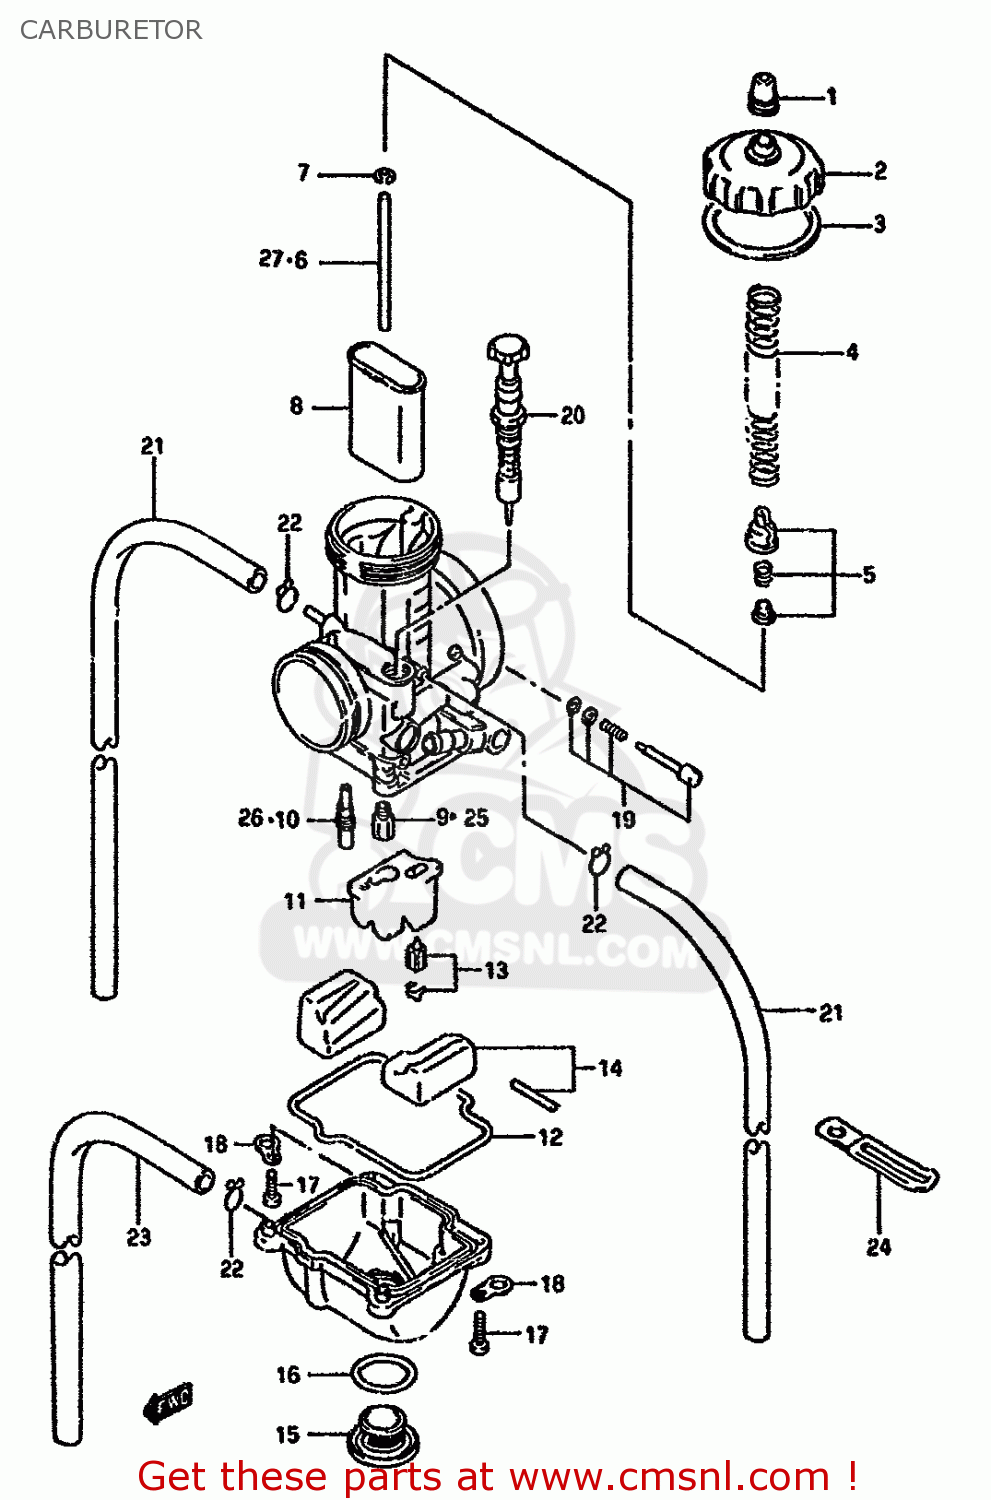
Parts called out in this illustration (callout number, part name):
1	CAP,CARBURETOR
2	CAP,TOP
3	GASKET,TOP CAP
4	SPRING
5	HOLDER SET,CABLE
6	NEEDLE(R1471MS)
7	CLIP,NEEDLE
8	VALVE,PISTON(CA:5.0)
9	JET,MAIN(155)
10	JET,SLOW(55)
11	HOLDER
12	GASKET,FLOAT CHAMBER
13	VALVE SET,FLOAT
14	FLOAT SET
15	BOLT,DRAIN
16	O RING
17	SCREW
18	PLATE
19	SCREW SET,AIR
20	PLUNGER ASSY
21	HOSE (4X7X440)
22	CLIP
23	HOSE (3.5X6.5X300)
24	CLAMP
25	JET,MAIN(145)
26	JET,SLOW(50)
27	NEEDLE(R1469MS)
